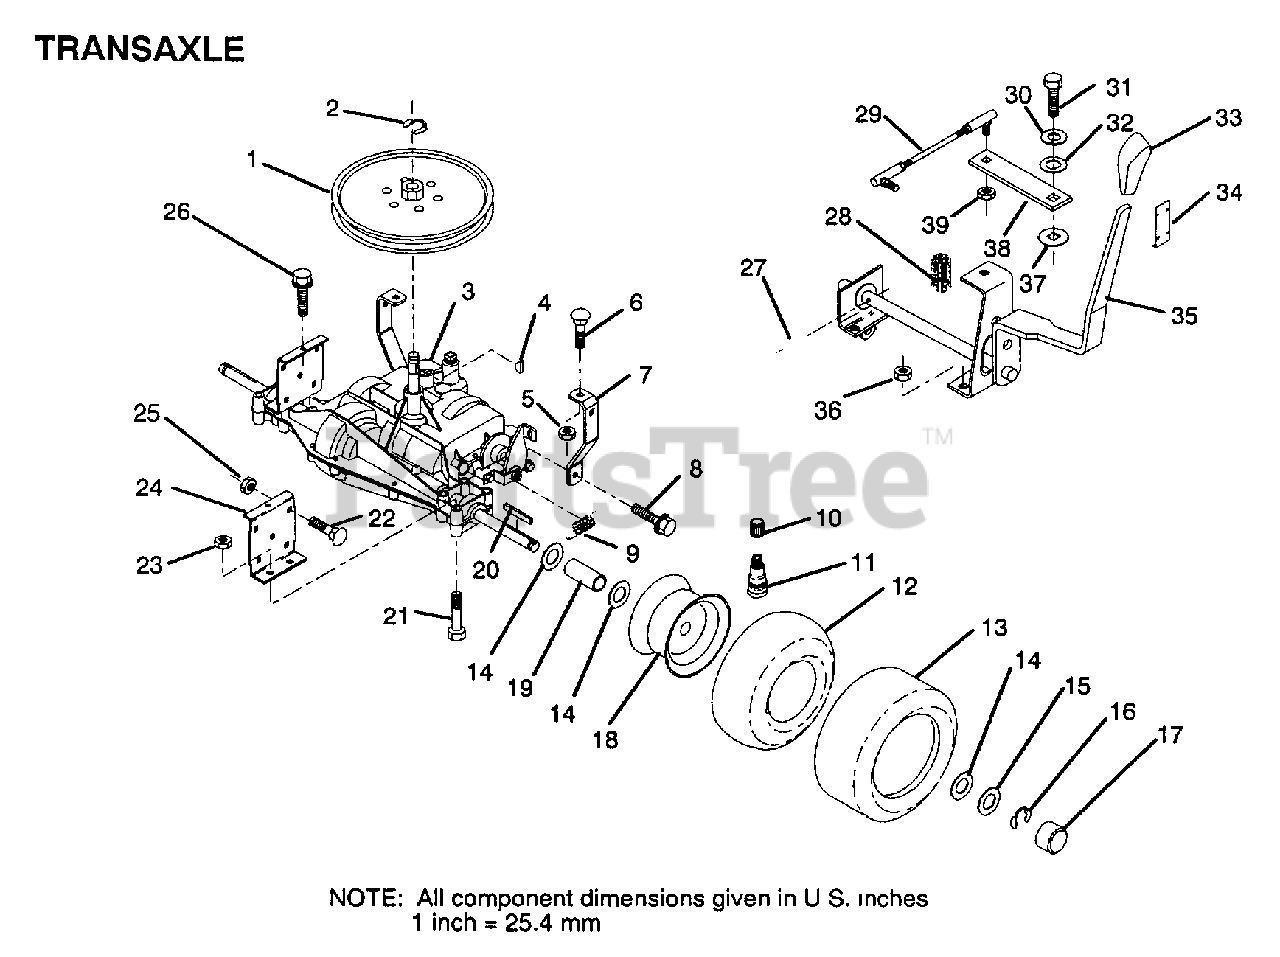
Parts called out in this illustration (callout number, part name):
1	PULLEY
6	BOLT
7	"STRAP,TORQUE"
8	SCREW LT
10	VALVE CAP
11	VALVE STEM LT
12	TUBE.16X6.5/7.5-8
14	WASHER
15	WASHER
16	E-RING LT
17	HUB CAP
19	SPACER
20	SQUARE KEY
21	BOLT
22	BOLT
24	"BRKT,TRANSAXLE"
26	SCREW
27	PIN COTTER 1/8
28	EXT SPRING
29	"LINK,SHIFT"
30	LOCKWASHER
32	WASHER LT
33	"KNOB,SHT CONTROL"
34	KNOB RETAINER
35	SHIFT HANDLE ASSY
37	WASH-SHFT PLT LT
38	"ARM,SHIFT"
39	NUT.LOCK.5/16-24
